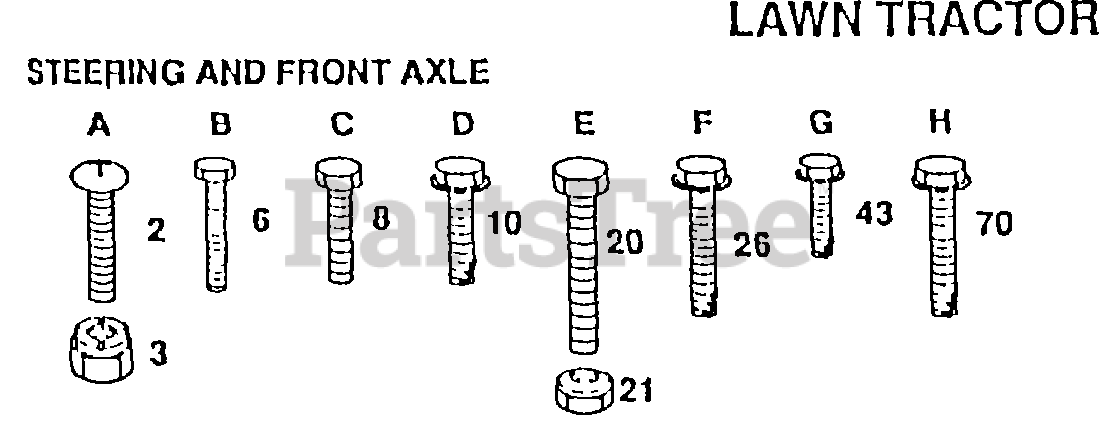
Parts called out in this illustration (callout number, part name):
2	SCREW
6	SCREW LT
10	SCREW LT
26	SCREW
43	SCREW LT
70	SCREW SPECIAL
